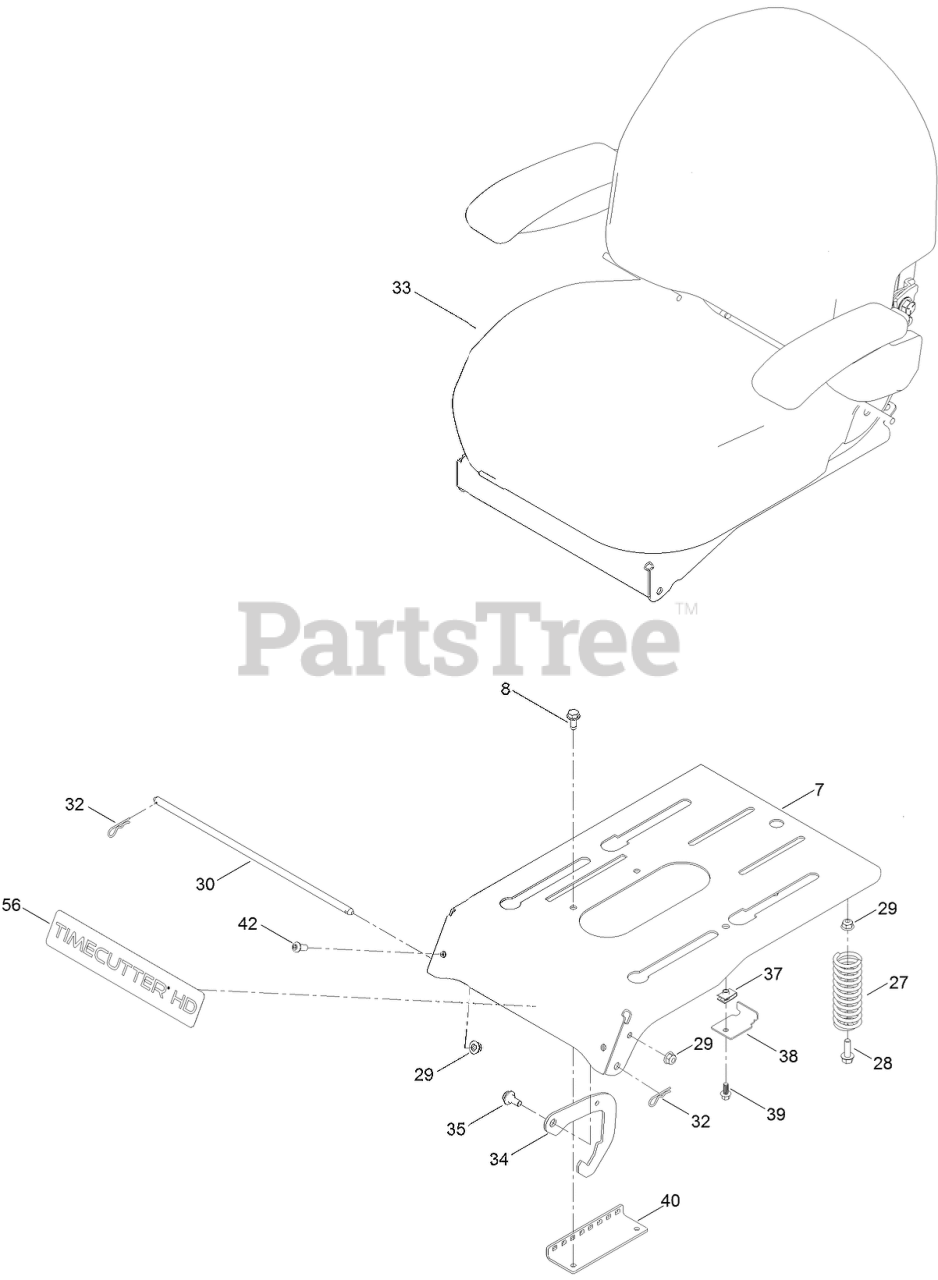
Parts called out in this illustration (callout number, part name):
7	PAN-SEAT, DELUXE
8	SCREW-HWHTF
27	SPRING-COMPRESSION
28	SCREW-HHF
29	NUT-HF
30	ROD-PIVOT, NARROW
32	PIN-COTTER
33	SEAT ASM
34	SEAT LATCH
35	SCREW-SHOULDER
38	BRACKET-STOP, SEAT
39	SCREW-HHF
40	BRACKET-LATCH, SEAT
42	SCREW-HSBH
56	DECAL-TIMECUTTER HD
